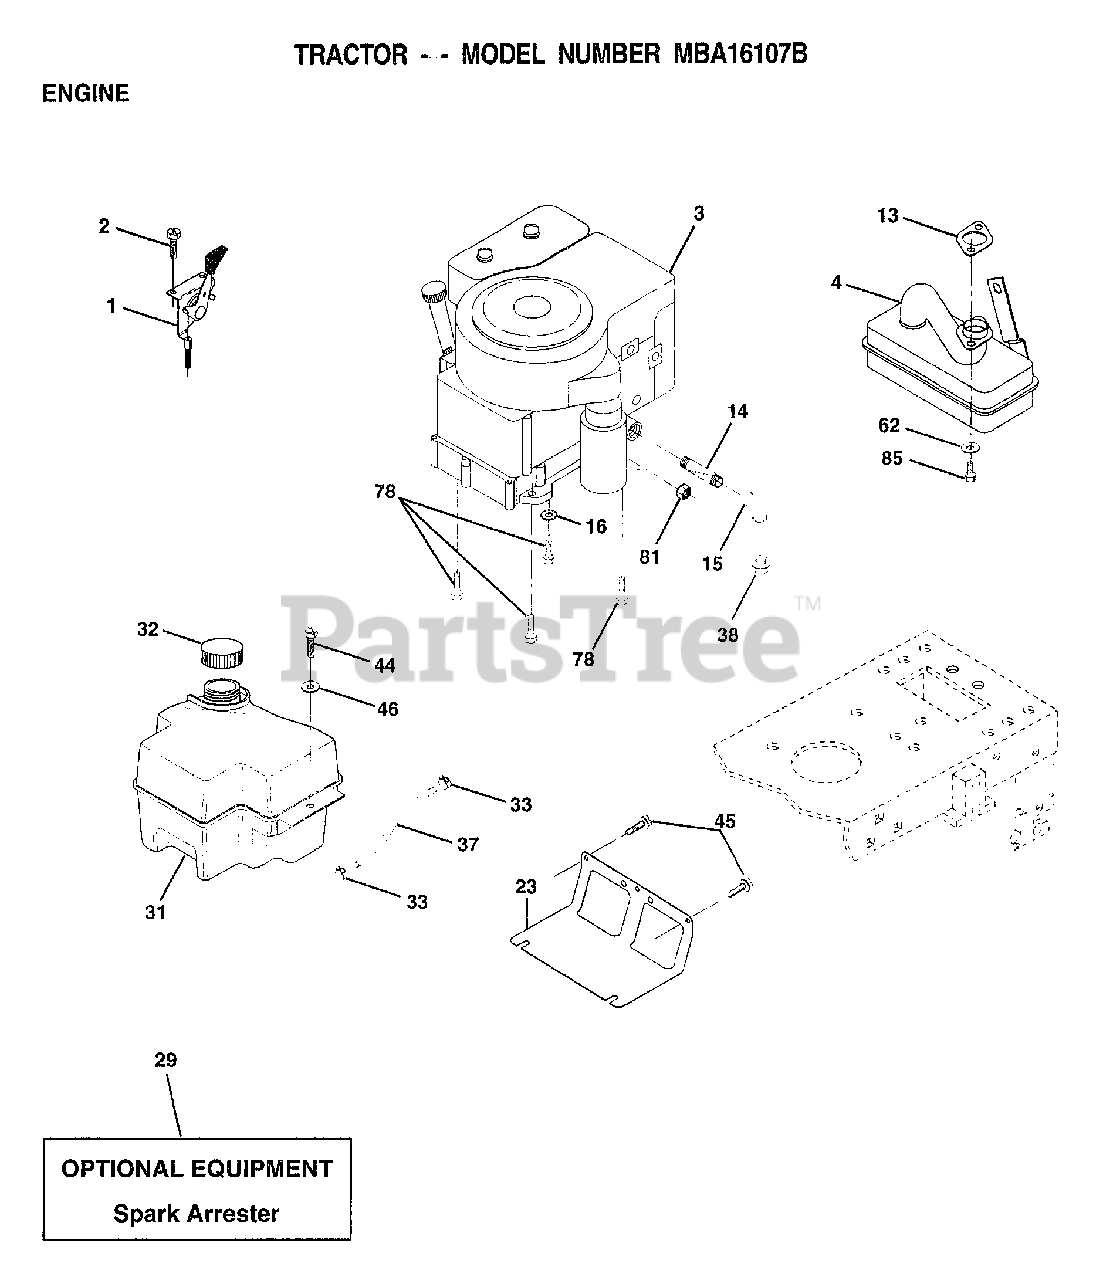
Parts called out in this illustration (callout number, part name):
1	CONTROL THROTTLE
2	SCREW LT
4	MUFFLER
13	GASKET MUFFLE TEC
14	PIPE NIPPLE LT
15	ELBOW
16	LOCKWASHER
23	SHIELD BROWNING
31	TANK.FUEL.FRONT.
32	CAP ASM FUEL
33	HOSE CLAMP
37	LINE FUEL
44	SCREW HEX CRT
45	SCREW
46	WASHER
62	LOCKWASHER
78	SCREW
81	NUT
85	SCREW HEX HD CAP
